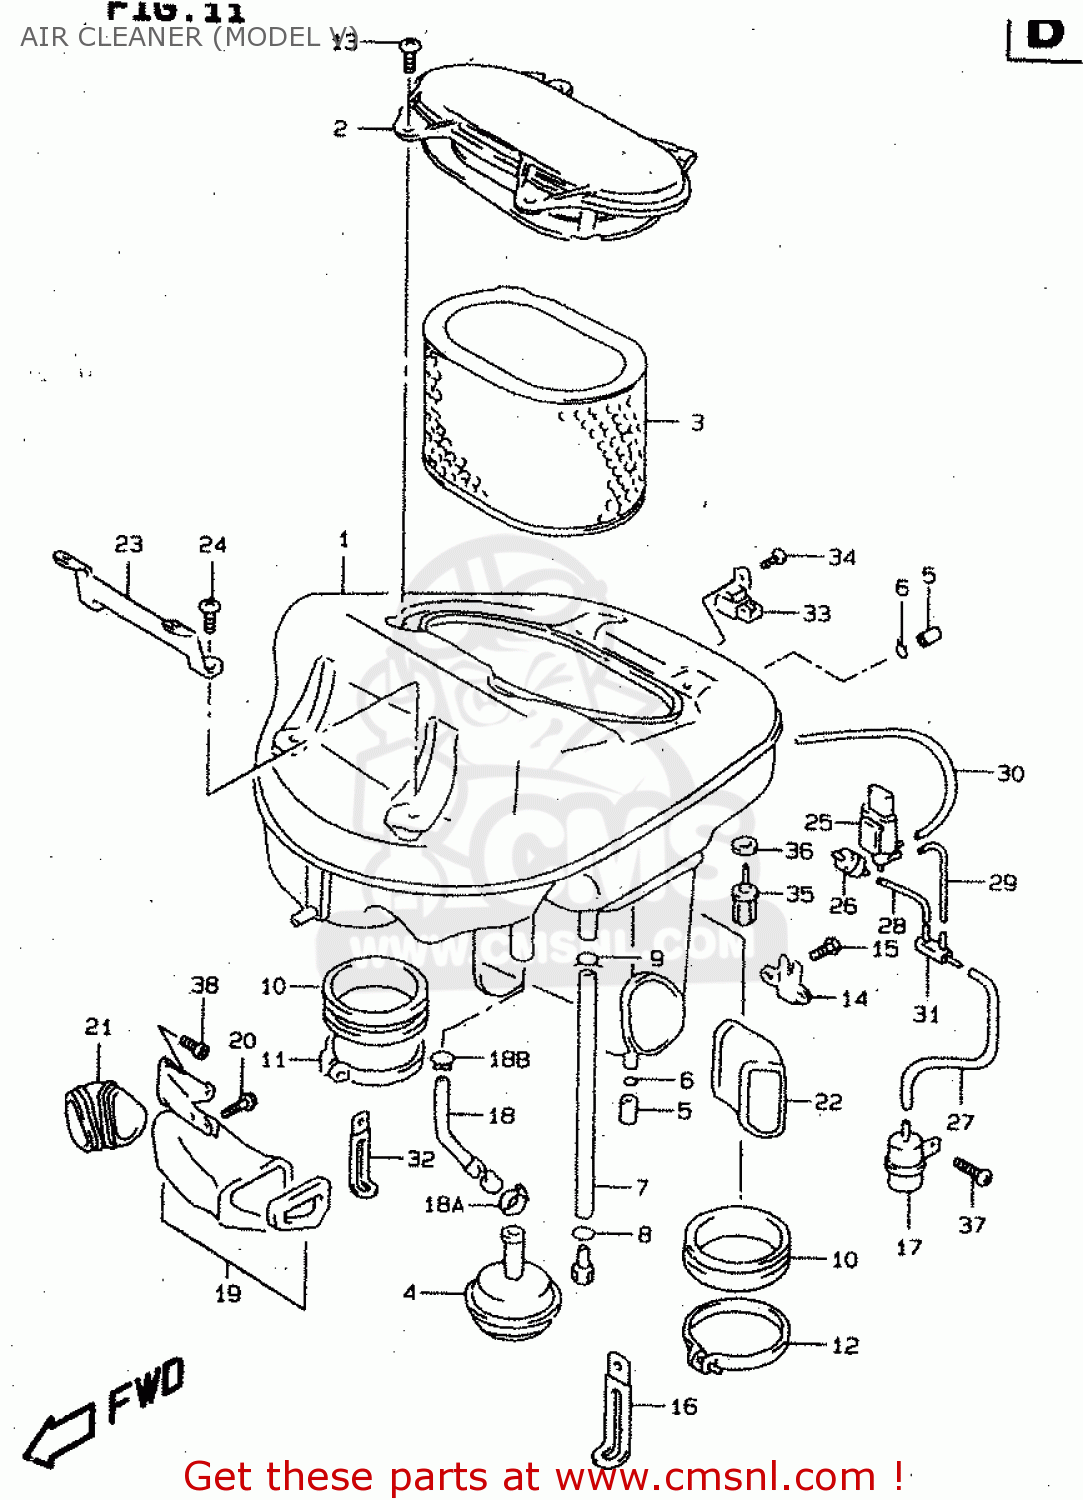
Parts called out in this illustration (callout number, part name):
1	CLEANER ASSY,AIR
2	CAP,AIR CLEANER
3	FILTER,AIR CLEANER
4	DIAPHRAGM,CONT VALVE
5	PLUG
6	CLIP
7	TUBE,DRAIN
8	CLIP
9	CLIP
10	TUBE,OUTLET
11	CLAMP
12	CLAMP
13	SCREW 5X12
14	BRACKET,SOLENOID VALVE
15	SCREW
16	CLAMP(L:65)
17	CHAMBER,VACUUM
18	TUBE,BREATHER
18A	CLAMP
18B	CLIP
19	DUCT,AIR CLEANER
20	BOLT
21	BOOT,AIR INLET,R
22	BOOT,AIR INLET,L
23	BRACKET,AIR CLEANER
24	SCREW 6X12
25	VALVE ASSY,3WAY SOLENOID
26	VALVE,CHECK
27	HOSE(4X8X600)
28	HOSE(4X8X600)
29	HOSE(4X8X600)
30	HOSE(4X8X600)
31	JOINT
32	CLAMP(L:80)
33	SENSOR,BOOST
34	SCREW
35	SENSOR,WATER TEMP
36	GASKET(12.2X21X0.8) (NAS)
37	SCREW 5X12
38	BOLT
